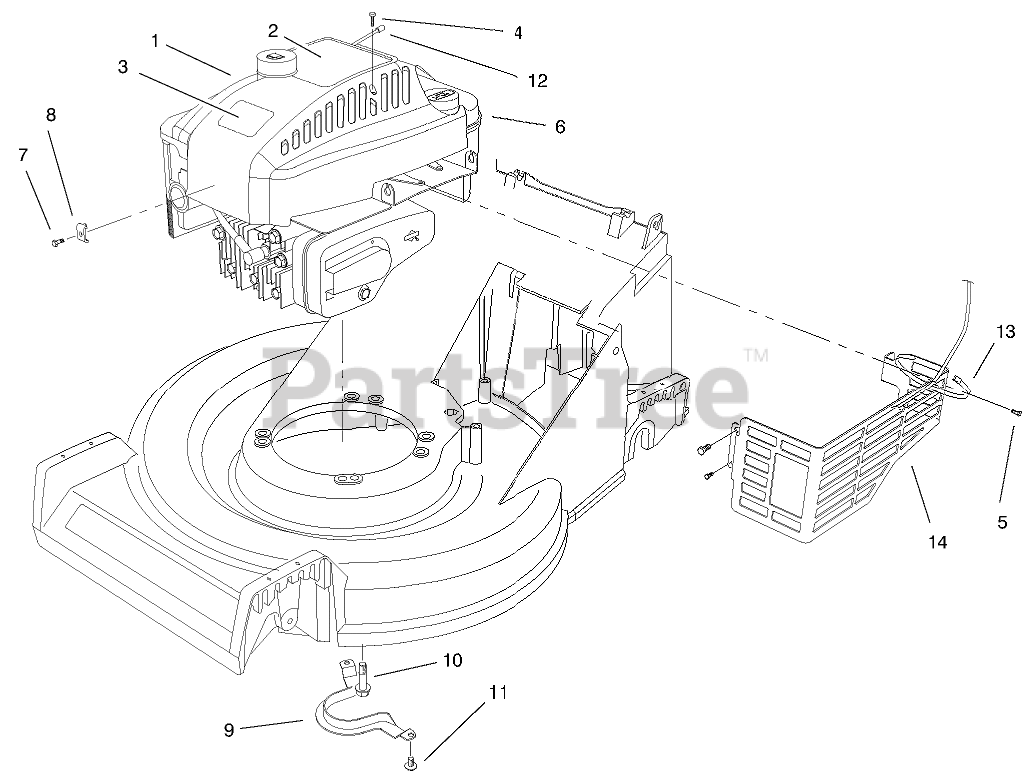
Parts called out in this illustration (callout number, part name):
1	SHROUD-ENGINE
2	DECAL - RECOIL
3	Decal
4	SCREW-PPH
5	SCREW-HWH
6	Engine-Quantum 6.0 Hp
7	SCREW-CLAMP
8	CLAMP-CASING
9	Guide-Belt
10	SCREW-HWH
11	SCREW-HWHTF
12	STOP-ROPE
13	TIE-CABLE
14	SHIELD-MUFFLER
